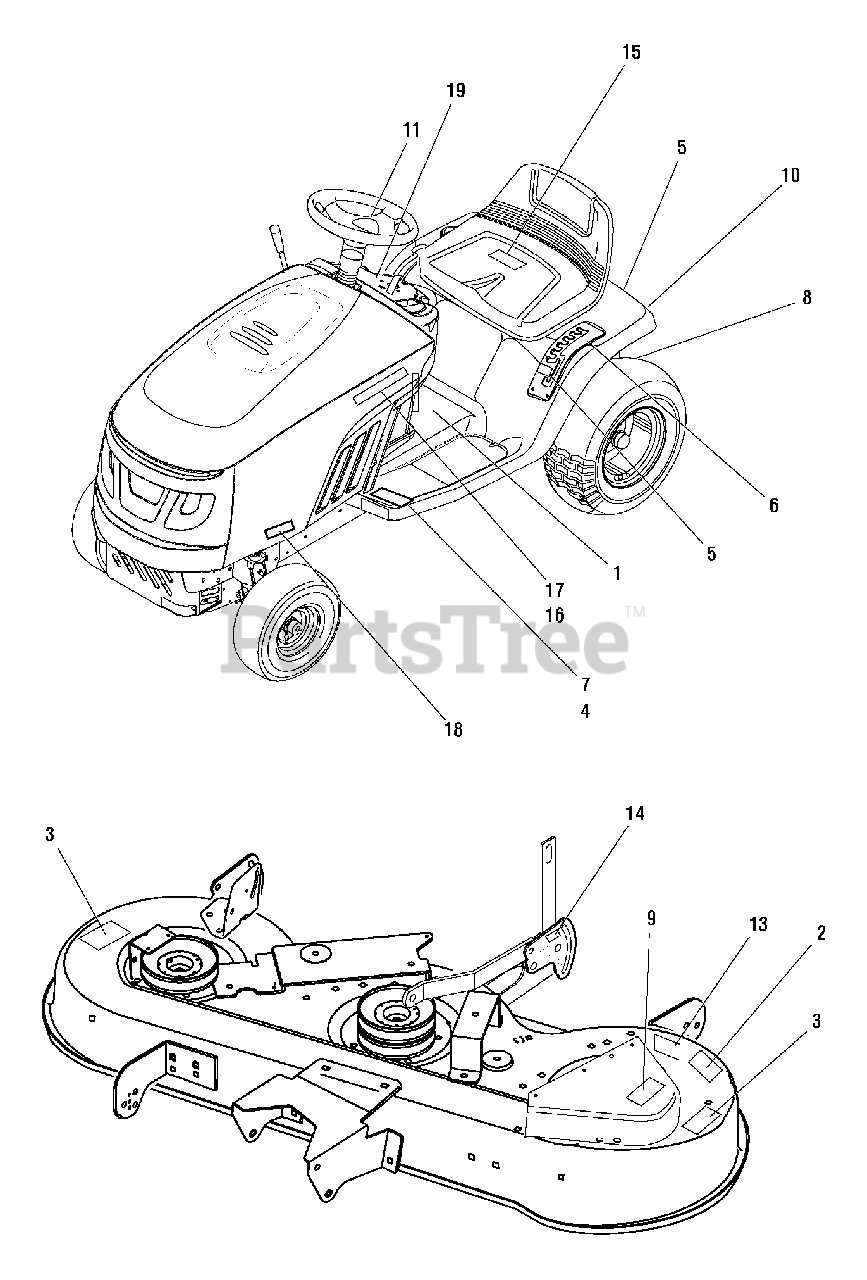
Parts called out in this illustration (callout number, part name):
1	DECAL, Umber
2	DECAL, No Step
3	DECAL, Danger Do Not Operate w/o Deflector
3	DECAL, Deck Symbols
4	DECAL, Drive Pedal
5	DECAL, Deck Level
6	DECAL, Height of Cut
7	DECAL, Belt/Clutch
8	DECAL, Weight Limitation
9	DECAL, 52 Deck
10	DECAL, Snapper Logo, Rear
11	DECAL, Snapper Logo, Steering Wheel
13	DECAL, Gage Wheel Instruction
14	DECAL, Gage Wheel Leveling
15	DECAL, Roll Release
16	DECAL, Snapper Name Plate, RH
17	DECAL, Snapper Name Plate, LH
18	DECAL, 23 hp
19	DECAL, Snapper Dash Panel Manual PTO
19	DECAL, Snapper Dash Panel
